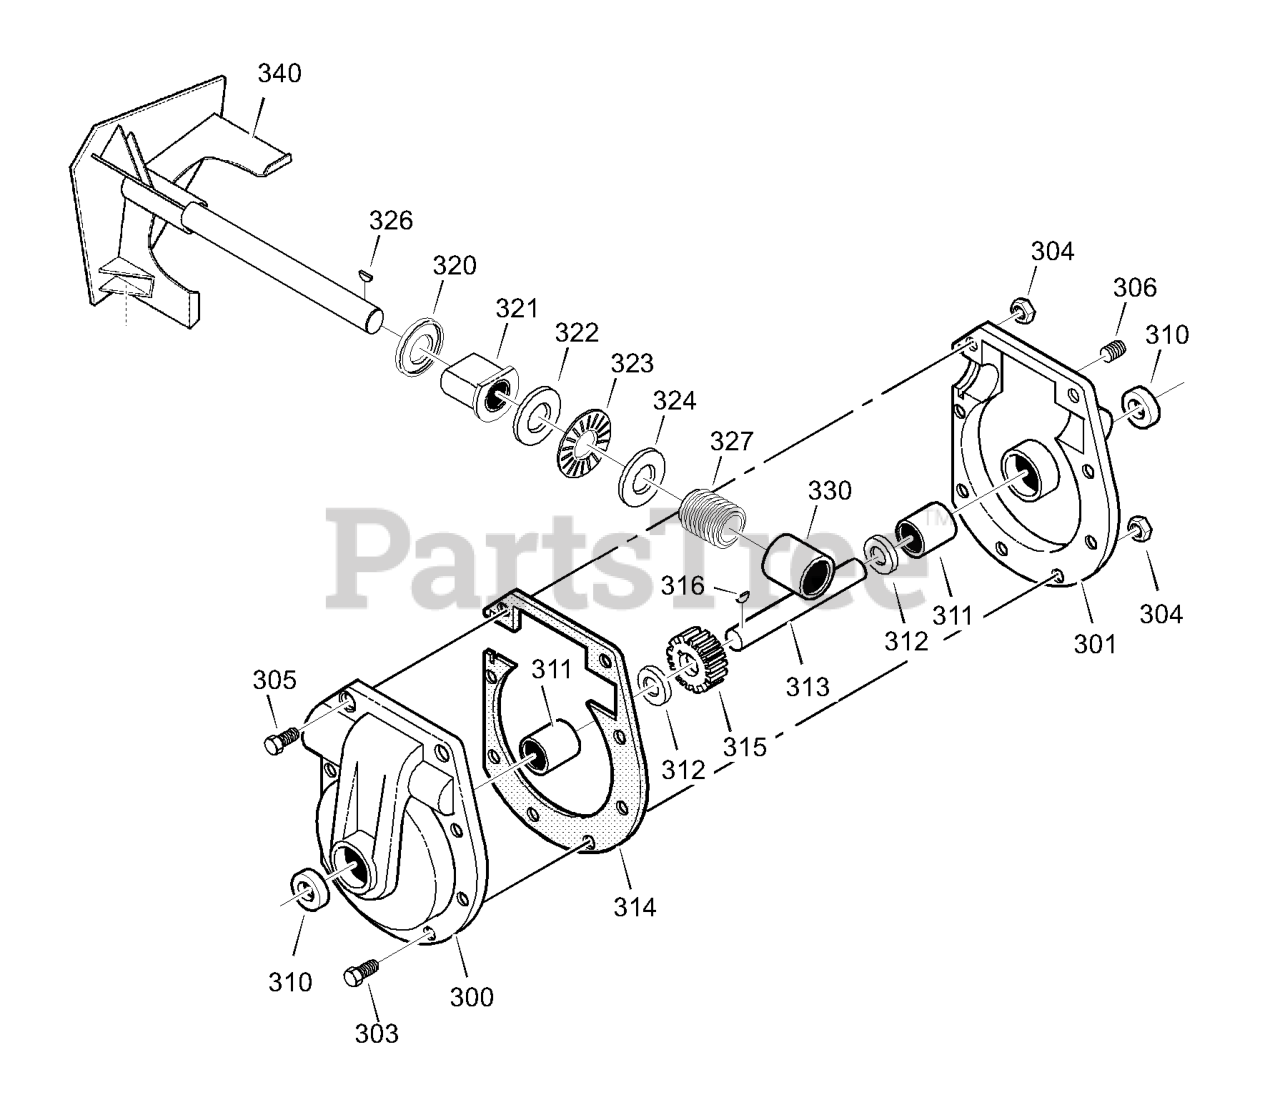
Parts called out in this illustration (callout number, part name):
300	CASE, GEAR, RH
301	CASE, GEAR, LH
303	SCREW,1/4-20X.75
304	NUT,1/4-20
305	SCREW, 5/16-24 x 1.50
306	PLUG, PIPE 1/4-18
310	SEAL, OIL
311	BEARING, FL
312	WASHER, FLAT
313	SHAFT, AUGER OUTPUT
314	GASKET, GEAR BOX
315	WORM GEAR
316	KEY, WOODRUFF #61
320	RING, QUAD
321	BEARING, FLANGE
322	WASHER, FLAT
323	BEARING, ROLL
324	WASHER, FLAT
327	GEAR, WORM
330	BEARING
